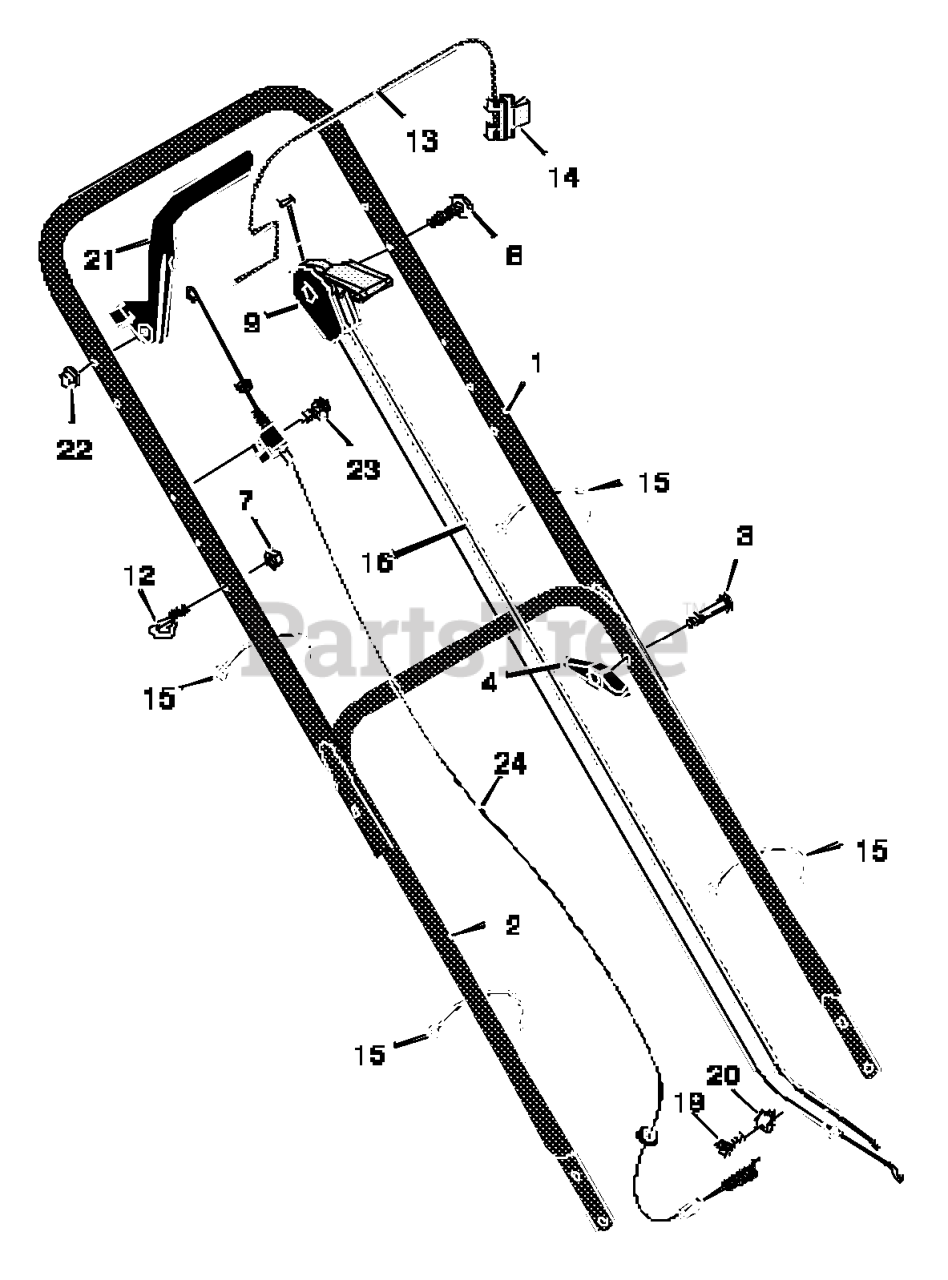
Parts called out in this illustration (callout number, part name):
1	Handle, Upper (Black)
2	Handle, Lower (Black)
4	Knob, Plastic
7	Locknut
9	Throttle Control
12	GUIDE, ROPE
13	Stop Lever - Straight
14	Bracket, Stop Lever
15	Fastener, Cable
16	Engine Stop Cable
21	Lever, Drive
22	Push On Cap
24	Cable, Drive
